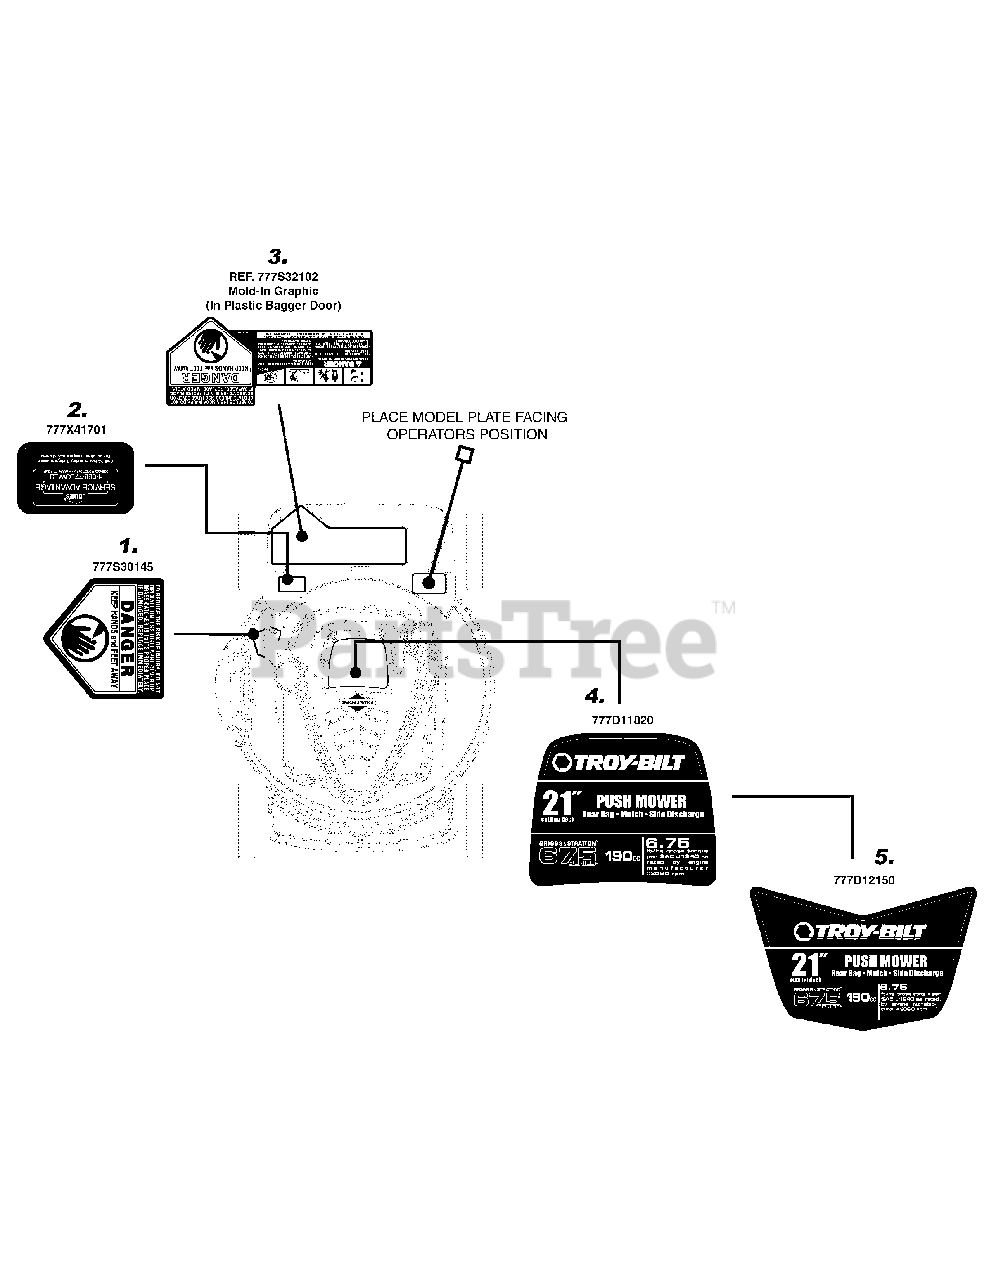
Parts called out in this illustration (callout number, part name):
1	LABEL
2	LBL:LOWES SERVICE ADVANTAGE
4	LABEL - TROY-BILT
5	LABEL - TROY-BILT
